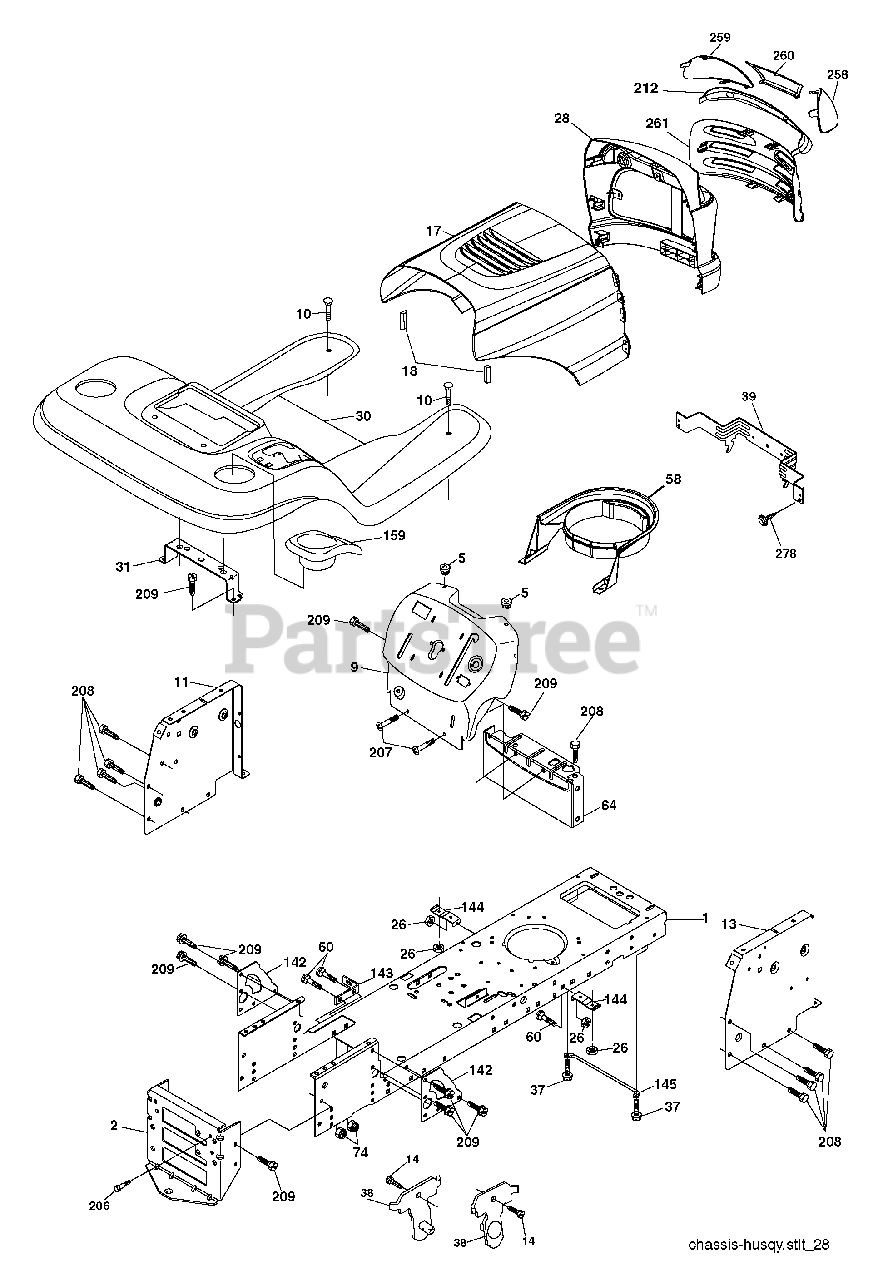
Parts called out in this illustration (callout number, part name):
1	Chassis
5	Bumper Hood/Dash
10	Bolt Carriage 3/8-16 x 1
11	Panel Dash Lh
13	Panel Dash Rh
14	Screw Thdrol 3/8-16 x 1/2
17	Hood
18	Bumper Hood 1.75
26	Nut Lock Hex W/Ins 3/8-16 unc
28	Grille/Lens Asm.
30	Fender Footrest
31	Bracket Fender
37	Screw Thdrol 6/16-18 x 1/2 TYT
38	Bracket Asm Pivot Mower Rear
39	Bracket Pivot Hood
60	Bolt RDHD Sqnk 3/8-16 unc x 3/4
64	Dash Lower STLT
74	Nut Crownlock 3/8-16 unc
142	Plate Reinforcement STLT
143	Bracket Swaybar Chassis
144	Bracket Footrest Step-thru
145	Rod Pivot Chassis/Hood
159	Cupholder
206	Bolt Shoulder 5/16-18
207	Screw 5/16-18 x 1/2
208	Screw Thdrl 3/8-16 x 1/2
209	Screw Hexwsh Thdr 3/8-16 x 3/4
212	Insert Lens
258	Lens RH
259	Lens LH
260	Cover Lens
261	Insert Grille
278	Screw 10 x 3/4 Single Lead-Hex
